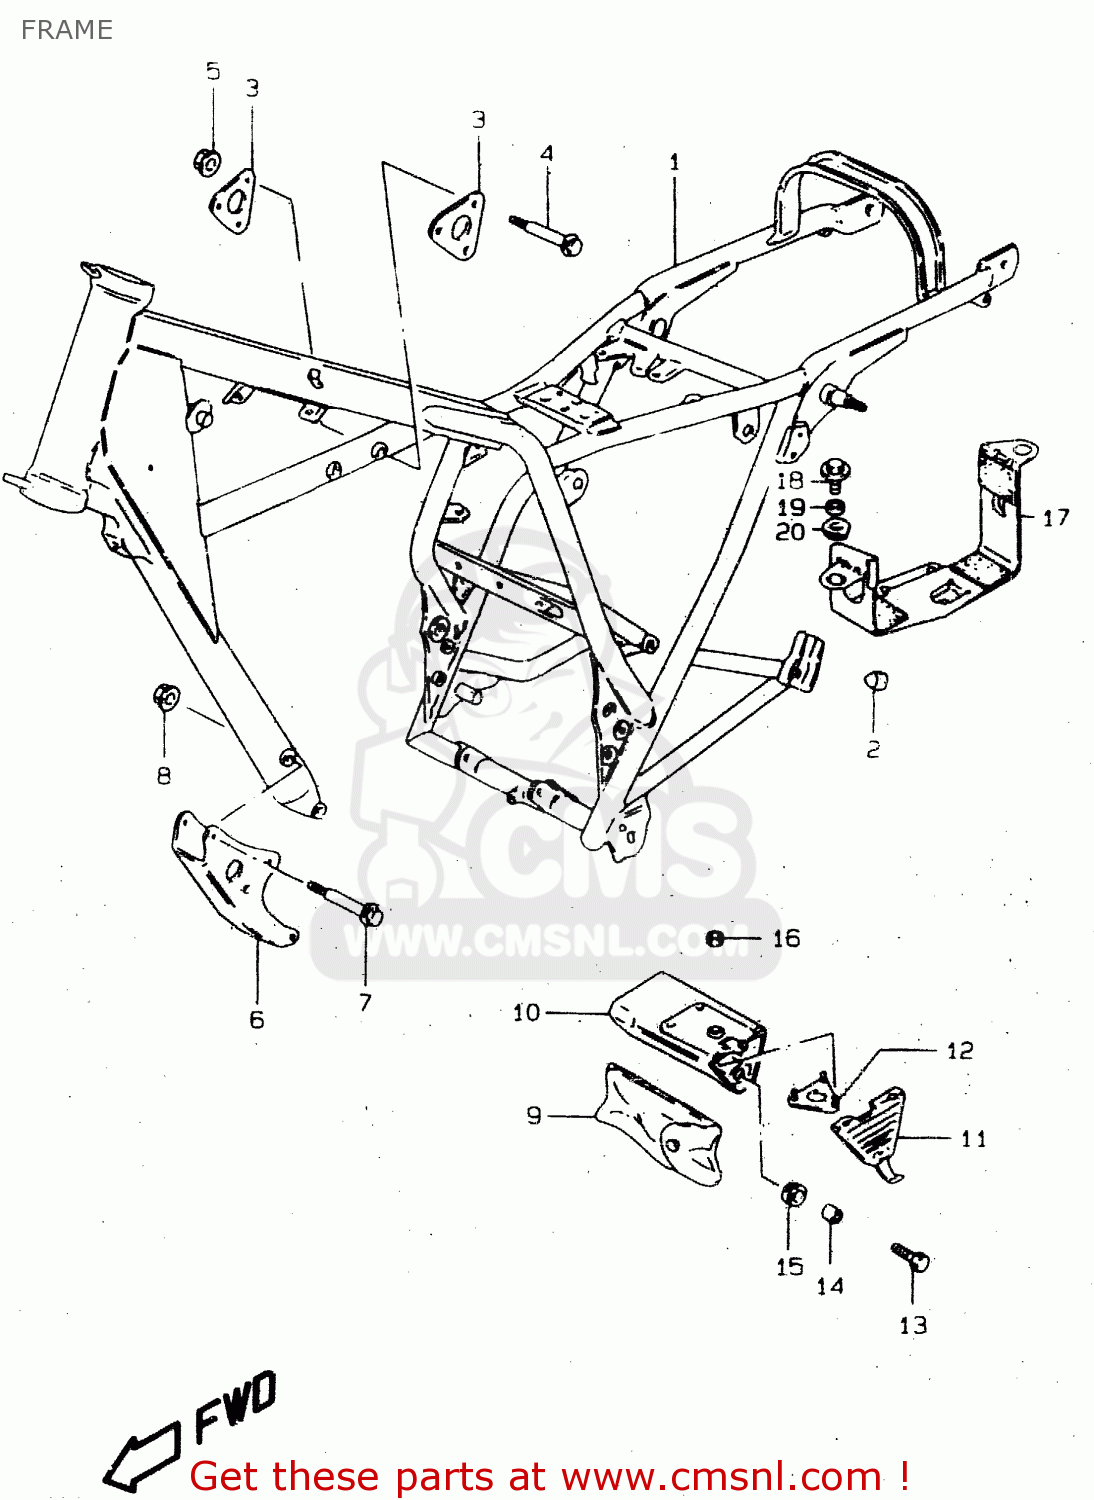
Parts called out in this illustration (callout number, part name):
1	FRAME(BLACK)
2	PLUG(OD:19)
3	PLATE,ENGINE MOUNT UPR
4	BOLT(8X50)
5	NUT
6	PLATE,ENGINE MOUNTING
7	BOLT
8	NUT
9	TOOL ASSY
10	BOX,TOOL
11	CAP,TOOL BOX
12	PLATE,TOOL HOLDER
13	BOLT(6X16)
14	SPACER(6.1X9X7.5)
15	CUSHION
16	NUT
17	HOLDER,BATTERY
18	BOLT(6X16)
19	SPACER(6.1X9X7.5)
20	CUSHION
